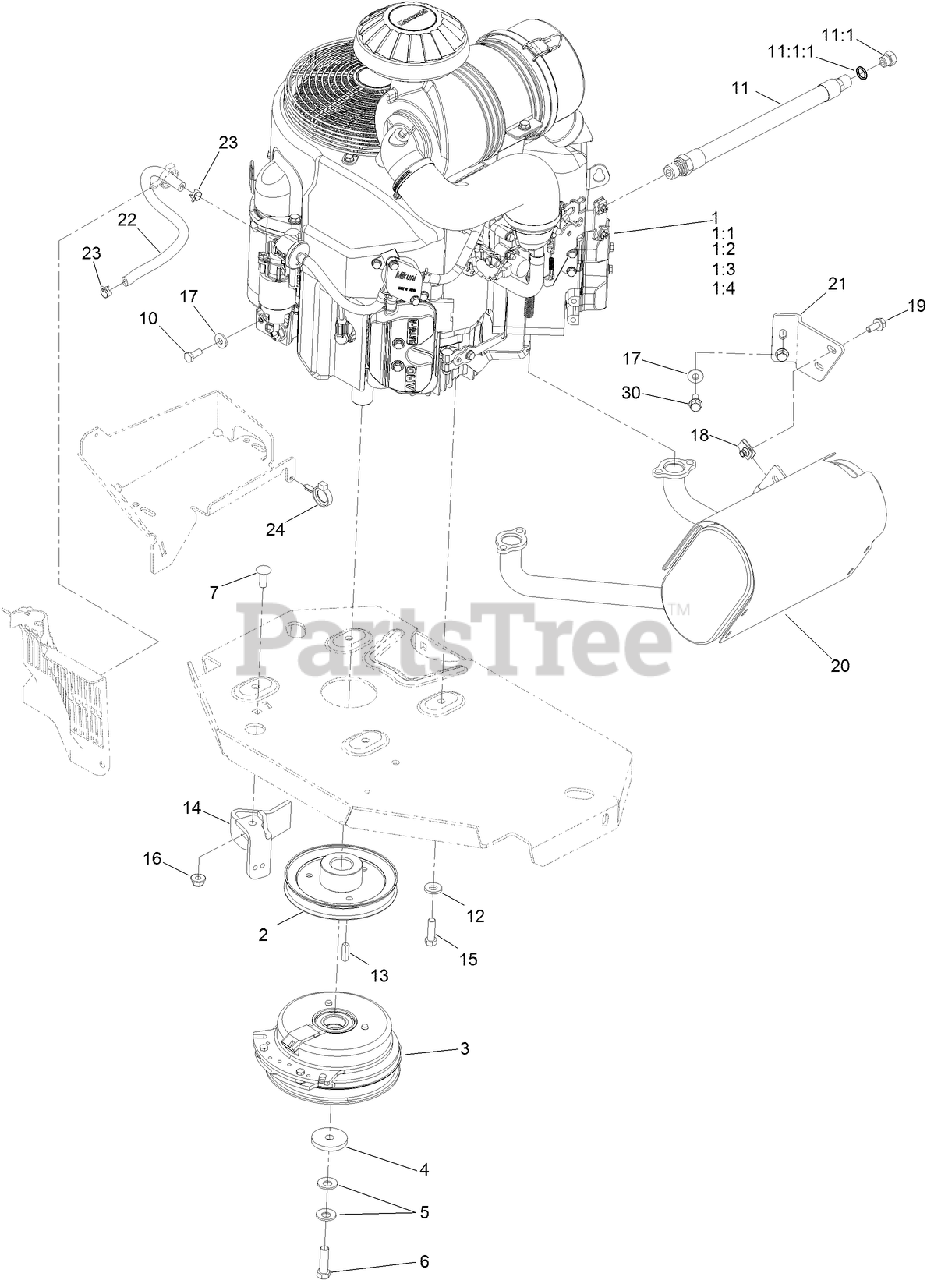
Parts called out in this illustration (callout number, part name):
1:1	KAWASAKI 49065-2078 ENGINE OIL FILTER
1:2	KAWASAKI 49019-7001 FUEL FILTER
1:3	KAWASAKI 11013-7039 SAFETY FILTER
1:4	KAWASAKI 11013-7038 AIR FILTER
2	SHEAVE
3	CLUTCH KIT
4	WASHER-CLUTCH
5	WASHER-SPRING
6	SCREW-HH
7	SCREW-CARR
10	SCREW-HH
11	ENGINE OIL DRAIN HOSE ASM
11:1	PLUG-HH
11:1:1	O-RING
12	WASHER-BELLEVILLE
14	CLUTCH-ANCHOR
15	SCREW-HH
16	NUT-HF, NI
17	WASHER-SPRING
18	NUT-U
19	SCREW-HHF
20	MUFFLER
21	BRACKET-MUFFLER
22	HOSE-FUEL
23	CLAMP-HOSE
24	CLAMP-HOSE
30	SCREW-HHF
